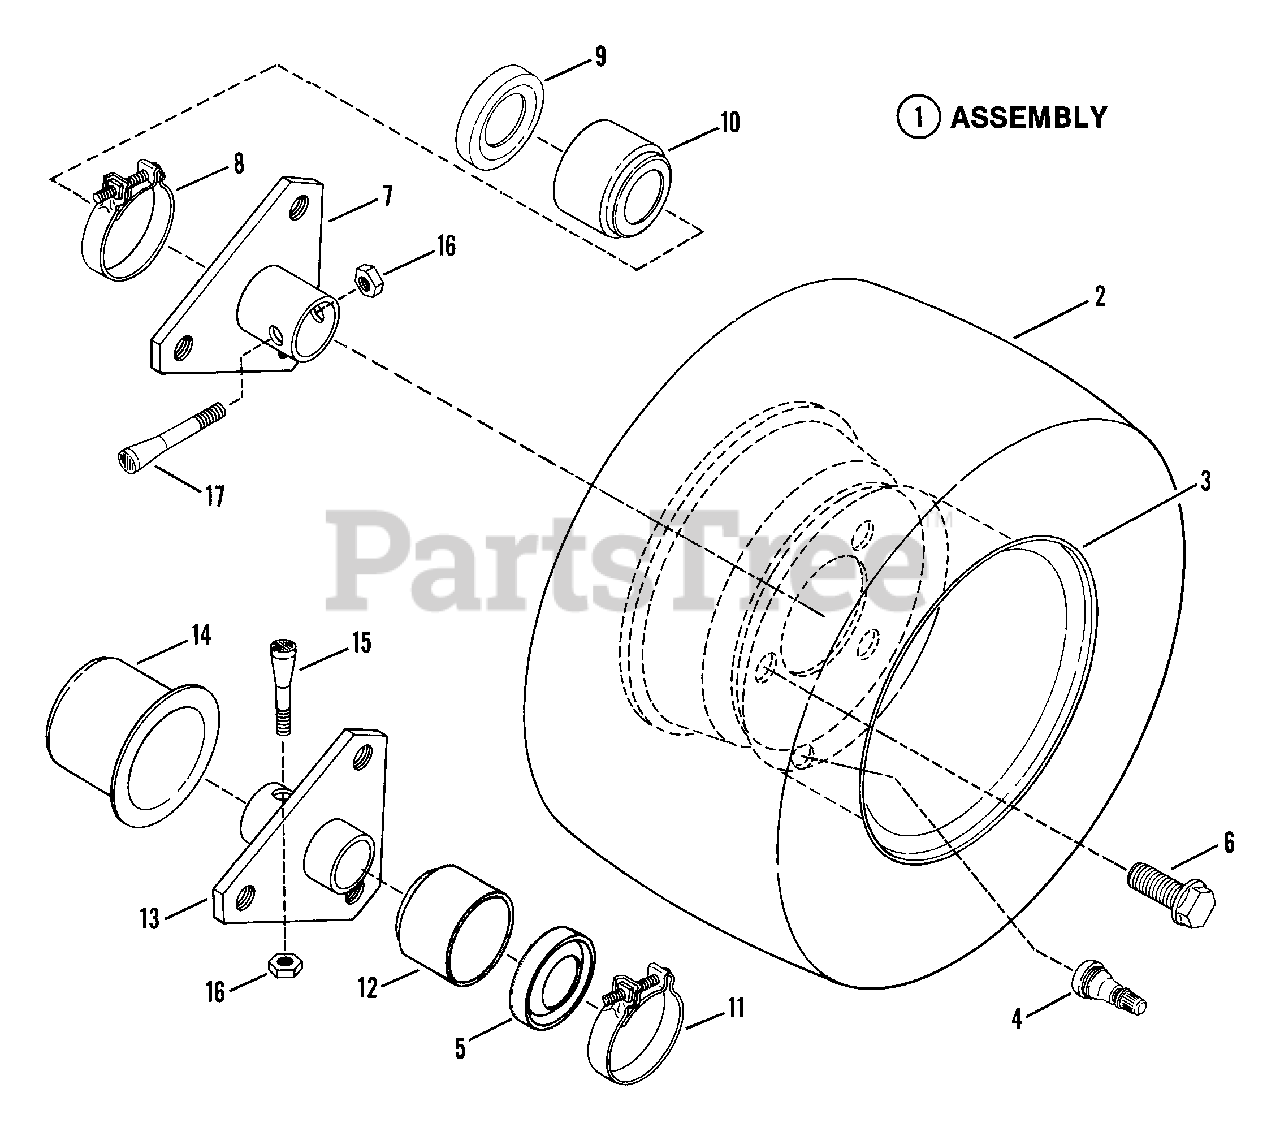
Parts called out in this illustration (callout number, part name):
1	ASSEMBLY, Rear Tire & Rim
2	TIRE, Wide, 16/6.50x8
3	RIM, Wide
4	VALVE, Air (Snap-in)
5	SEAL, Oil Left Hand (.75" ID)
6	BOLT, 1/2-20x3/4" Lug
7	HUB, Rear Wheel, Right Hand (1.25" ID)
8	CLAMP, Right Hand (3" ID)
9	SEAL, Oil, Right Hand (1.12" ID)
10	BOOT, Right Hand
11	CLAMP, Left Hand (2+/-" ID)
12	BOOT, Left Hand
13	HUB, Rear Wheel, Left Hand (.75" ID)
14	HUB-CAP, Left Hand
15	BOLT, 5/16-24x1-5/8" Tapered, Left Hand
16	NUT, 5/16-24 Lock
17	BOLT, 5/16-24x2" Tapered, Right Hand
